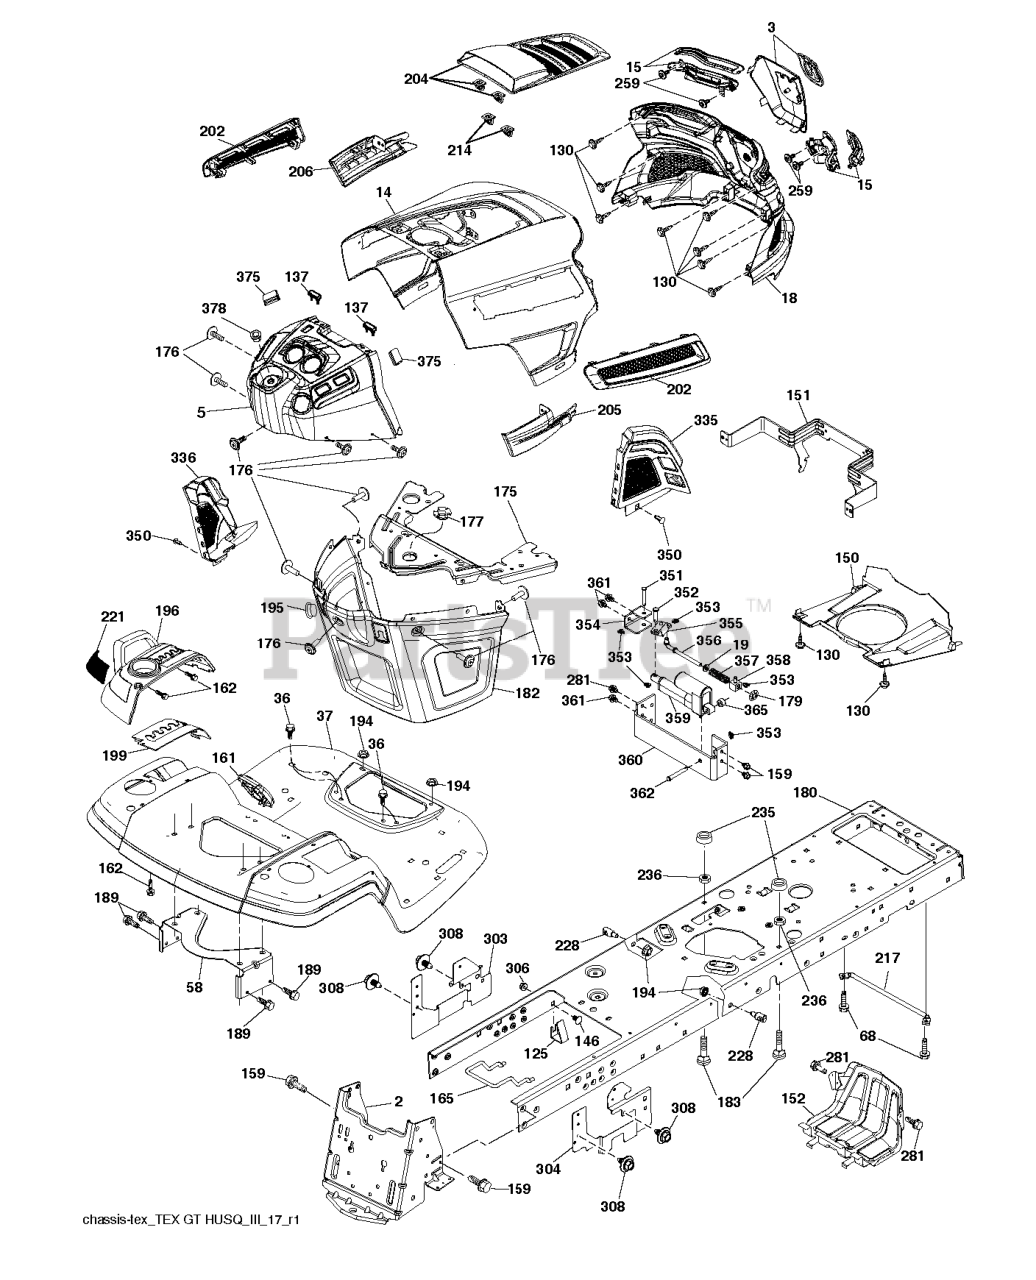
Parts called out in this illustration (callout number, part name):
2	DRAWBAR.STGT
5	DASH.UPPER.ASM.GT2.D_R.PTO.ELC
14	HOOD.ASM.HUSQVARNA.GT.TEX.ORAN
15	Service Kit
36	SCREW 5/16"
37	FENDER.PNT.TX.GT.CH/FW/DL.HUSQ
58	BRKT.SUPPORT.FNDR/TANK
125	CLIP.FUEL.LINE
137	BUMPER DASH
146	BOLT.RDHD.SHT.SQNK.3/8-16X5/8
150	AIR.DUCT.GTV.BLACK
151	BRACKET.PIVOT.HOOD.GT.HUSQ.II
152	SHIELD.BROWNING.PNT.GT.V2
159	SCREW, 3/8-16X3/4
161	CONSOLE.WINDOW.FUEL.HUSQ.GT
165	SUPPORT.TANK.REAR.B/TE
175	PLATE.PNT.CROSSMEMBER.HUSQ/PRE
176	SCREW.#10-24X5/8.RN.QU
177	BUSHING STEERING
180	CHASSIS.LT/GT.BOLTED
182	DASH.LOWER.COMMON.12V.ADAPTOR
189	SCREW
195	PLUG.HOLE.DASH.LOWER.12V.BLK
196	SUBASM.CONSOLE.HUSQ.GT.DECKLFT
199	PLATE.DECK.LIFT.HUSQVARNA.GT
202	Vents
205	SIDE.TRIM.RH.GT.HUSQ.II
206	SIDE.TRIM.LH.GT.HUSQ.II.GRAY
214	CLIP.RETAINER.TINNER.
217	ROD.PIVOT.HOOD
221	REFLECTOR.LH.TEX GT HU
228	STUD.W/"D"ANTI-ROTATION
236	NUT.CENTERLOCK.5/16-
281	SCREW 3/8-16X1
303	SHIELD.LWR.LH.LTGT.NON30
304	SHIELD.LWR.RH.LTGT.NON30.NOTCH
306	NUT LOCK FLG 3/8-16 UNC
308	BOLT.5/16-18UNCX3/4 W/SEMS.BLK
335	COVER.LOWER.DASH.RH.BLACK
336	COVER-LH.LOWER.DASH.GT2.BLACK
350	CLIP.X-MAS.TREE
351	PIN.CLEVIS.375X2.125
352	PIN.CLEVIS.(.375 X 1.25)
353	CLIP RETAINER
354	SUPPORT.DIFF.LOCK.BELLCRANK.
355	BELLCRANK.PIVOT.LOCK.DIFF
356	LINK.LOCK.DIFF
357	SPRING.COMPRESSION
358	SWIVEL.GUIDE
359	ACTUATOR.ELECTRIC
360	BRACKET.ACUATOR
362	PIN.CLEVIS.(.375 X 2.42)
365	SPACER.NYLON.75" X .4375
375	BUMPER CLIP-ON. DASH 1"
378	BUSHING FLANGE; PLASTIC
